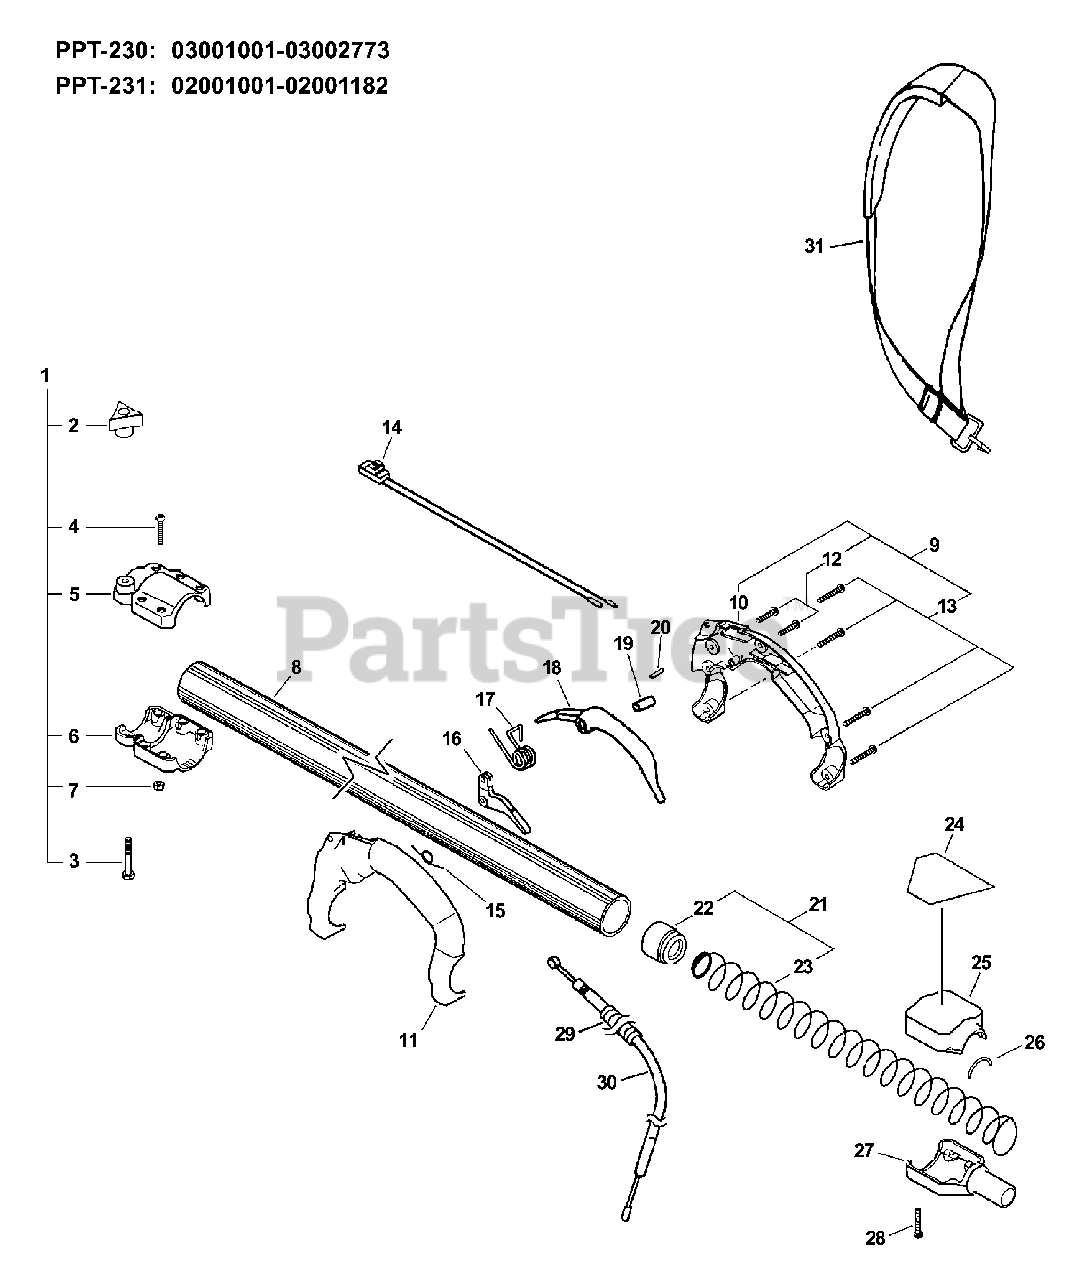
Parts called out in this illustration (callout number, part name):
1	COLLAR ASSY
2	THUMBSCREW
4	SCREW - 10-24 X 1-1/4"
5	COLLAR, MAIN PIPE - UPPER
6	COLLAR, MAIN PIPE - LOWER
7	LOCKNUT - 10-24
8	PIPE, MAIN - ORANGE
9	HANDLE ASSY - REAR
10	HANDLE, REAR - LEFT
11	HANDLE, REAR - RIGHT
12	SCREW - 10-24 X 7/8"
13	SCREW - 10-24 X 1-1/4"
14	IGNITION SWITCH ASSY
15	SPRING, TRIGGER
16	TRIGGER, THROTTLE
17	SPRING, LOCKOUT LEVER
18	LOCKOUT, THROTTLE
19	COLLAR - 5
20	PIN - LOCATING
21	FLOATING BUSHING ASSY
22	BUSHING, FLOATING
24	LABEL - CAUTION
25	LOWER HSNG ADAPT (TOP)
27	ADAPTER, LOWER SHAFT TUBE
28	SCREW - 10-24 X 1-1/4"
29	TUBE, PROTECTIVE - CORRUGATED
30	CABLE, THROTTLE
31	SHOULDER STRAP ASSY
